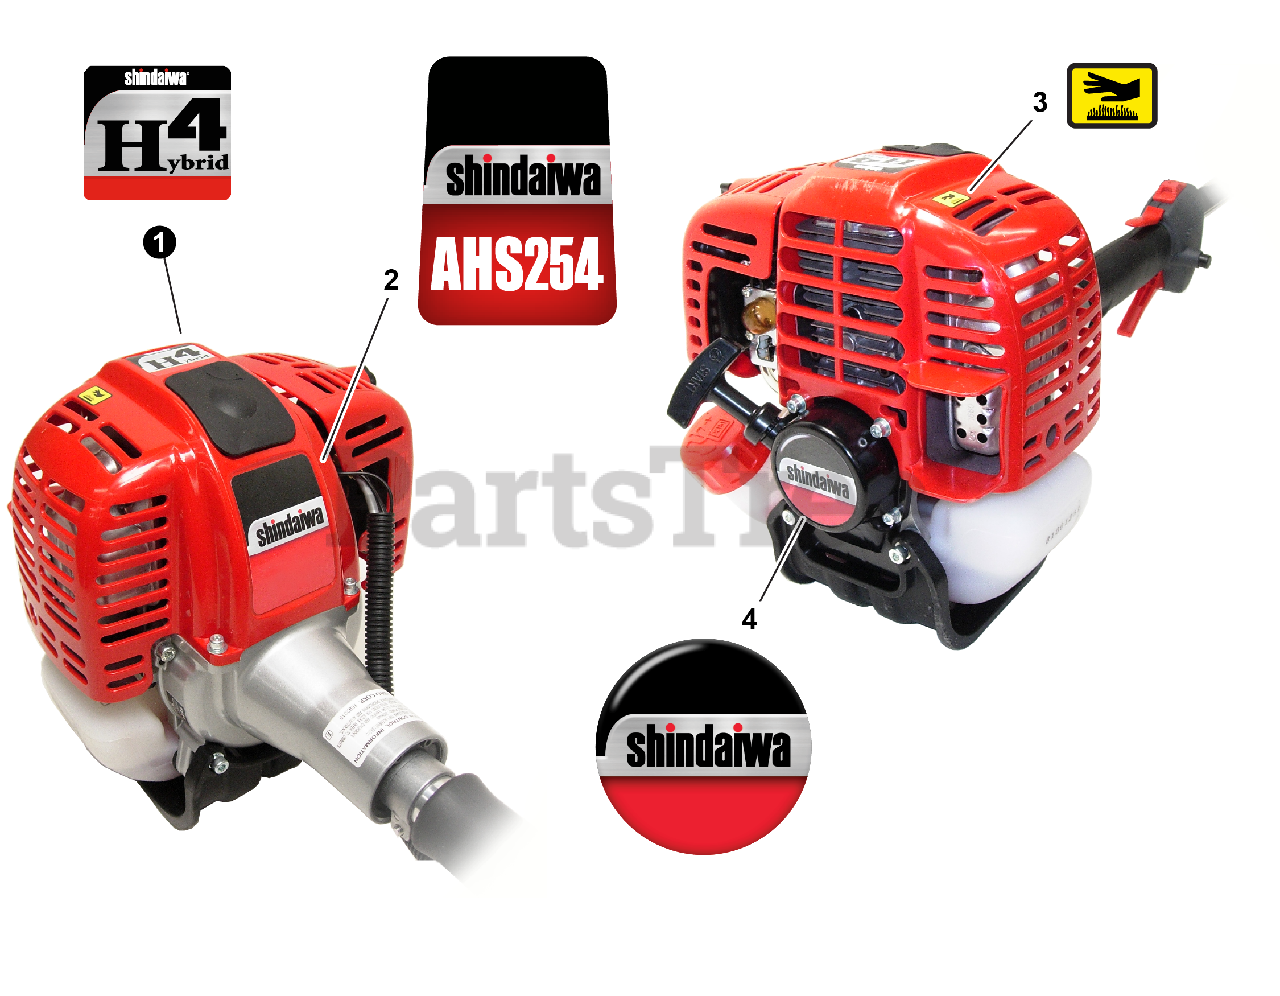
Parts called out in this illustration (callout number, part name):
1	LABEL, shindaiwa H4
2	LABEL, AHS254
3	LABEL, CAUTION - HOT
4	LABEL, RECOIL STARTER
